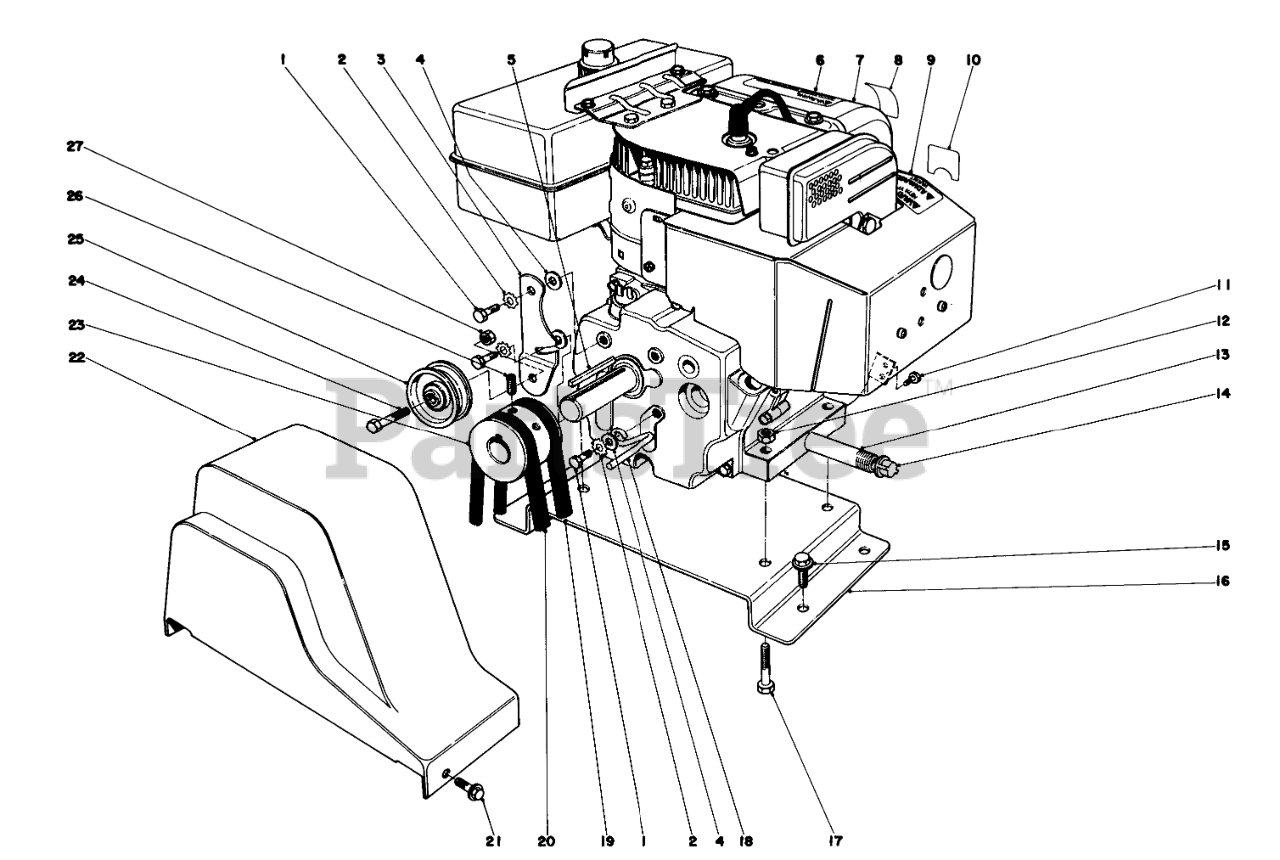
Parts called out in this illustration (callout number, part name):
1	SCREW-HH
2	WASHER-LOCK
3	ENGINE IDLER ARM
4	WASHER-PLAIN
6	HAZARDS CAUTION DECAL
7	Engine
8	Decal-Primer
9	Decal
10	CHOKE DECAL
11	SCREW
12	NUT-LOCK, NI
13	NIPPLE-PIPE
14	CAP-PIPE
15	SCREW-HHFTF
16	Plate ngine Mounting
17	SCREW-HH
18	BELT RETAINER
19	V-BELT
20	V-BELT
21	SCREW-HWH
22	BELT GUARD
23	ENGINE PULLEY
24	SCREW-HH
25	PULLEY-IDLER
26	Screw-Set
27	NUT-HEX
